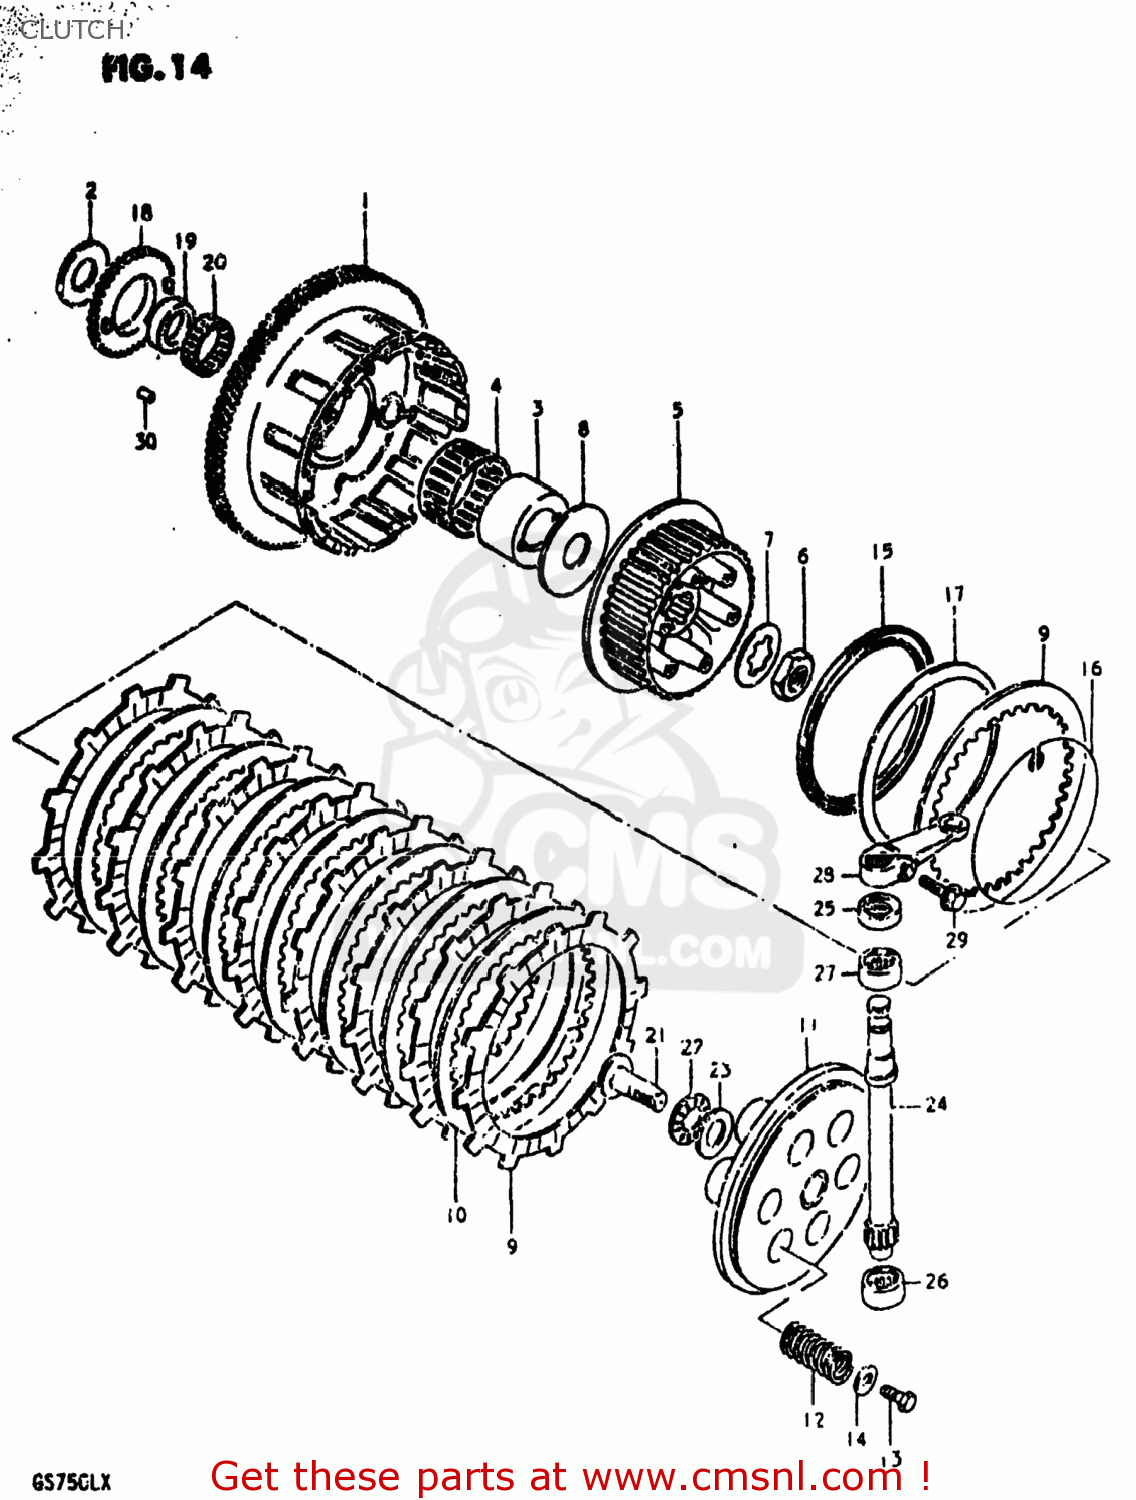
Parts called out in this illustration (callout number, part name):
1	GEAR ASSEMBLY,PRIMARY DRIVE
2	WASHER
3	SPACER,PRIMARY DRIVEN
4	BEARING
5	HUB,CLUTCH SLEEVE
6	NUT
7	WASHER,LOCK
8	WASHER(25X66X3.5)
9	PLATE,CLUTCH DRIVE (MCA)
10	PLATE,CLUTCH DRIVEN(T:2.0) (NAS)
11	DISC,CLUTCH PRESSURE
12	SPRING
13	BOLT, UPPER
14	WASHER
15	SEAT,WAVE WASHER
16	RING,STOPPER
17	WASHER
18	GEAR,ENG OIL PUMP DRIVE(NT:38)
19	SPACER,OIL PUMP DRIVE GEAR
20	BEARING(36X40X10)
21	RACK,CLUTCH RELEASE
22	BEARING(15X28X2)
23	WASHER
24	PINION,CLUTCH RELEASE
25	OIL SEAL
26	BEARING(12X19X12)
27	BEARING(15X22X12)
28	ARM,CLUTCH RELEASE
29	BOLT,REAR
30	CUSHION,PRIMARY DRIVEN GEAR
